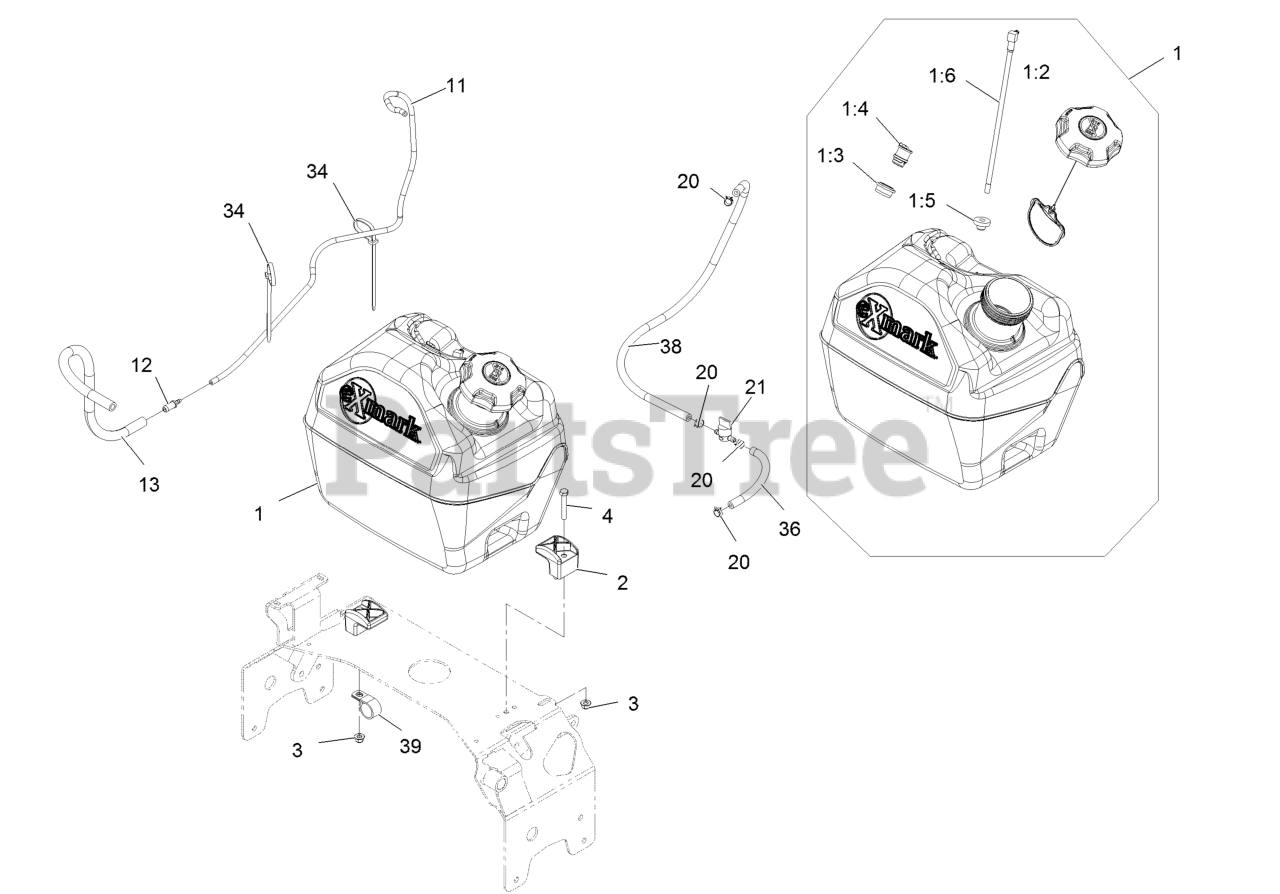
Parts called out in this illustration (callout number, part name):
1	ASM, Fuel Tank 5 Gal
1:2	Cap-Fuel, Ratcheting
1:3	Grommet
1:4	Valve-Vent, Fuel
1:5	Bushing
1:6	Fitting-Fuel (W/Line And Screen)
3	Nut-Nyloc 5/16-18 Flg
4	Screw-HH 5/16-18 X 2
11	Hose, Emissions
12	Fitting-Straight
13	Hose-Fuel
20	Clamp-Hose
21	Valve-Fuel
34	Tie-Cable 7 15/16 (Large)
36	Hose-Fuel
38	Hose-Fuel Line 32"
39	Clip-Loom
